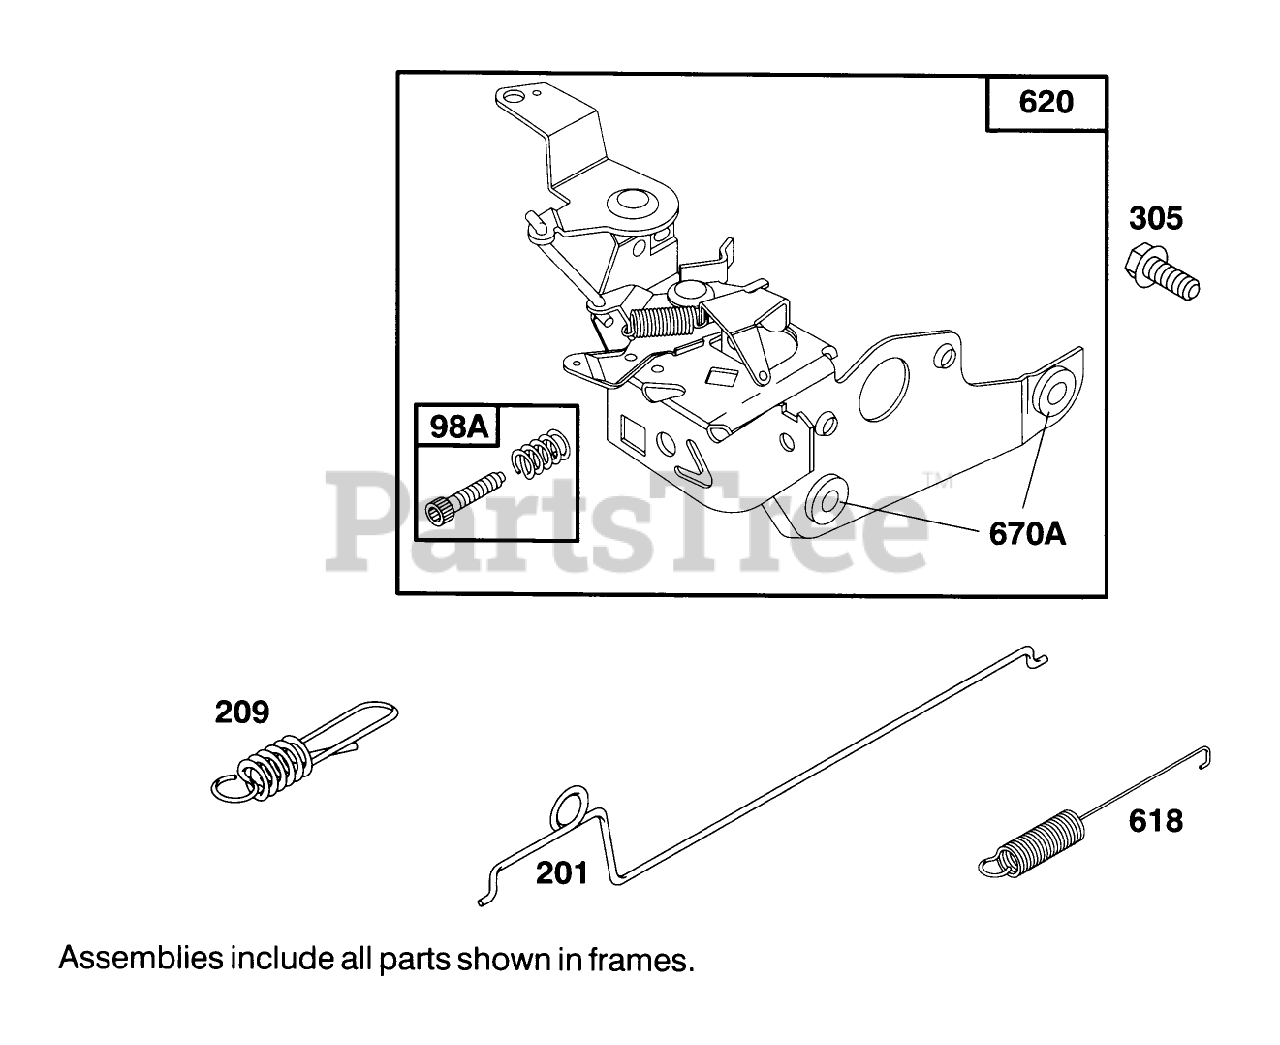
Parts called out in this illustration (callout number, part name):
98A	Screw Assy.
201	Link-Govemor
209	Spring-Govemor
305	Screw-Sem
618	Spring-Choke
620	Bracket Assembly
670A	Spacer
